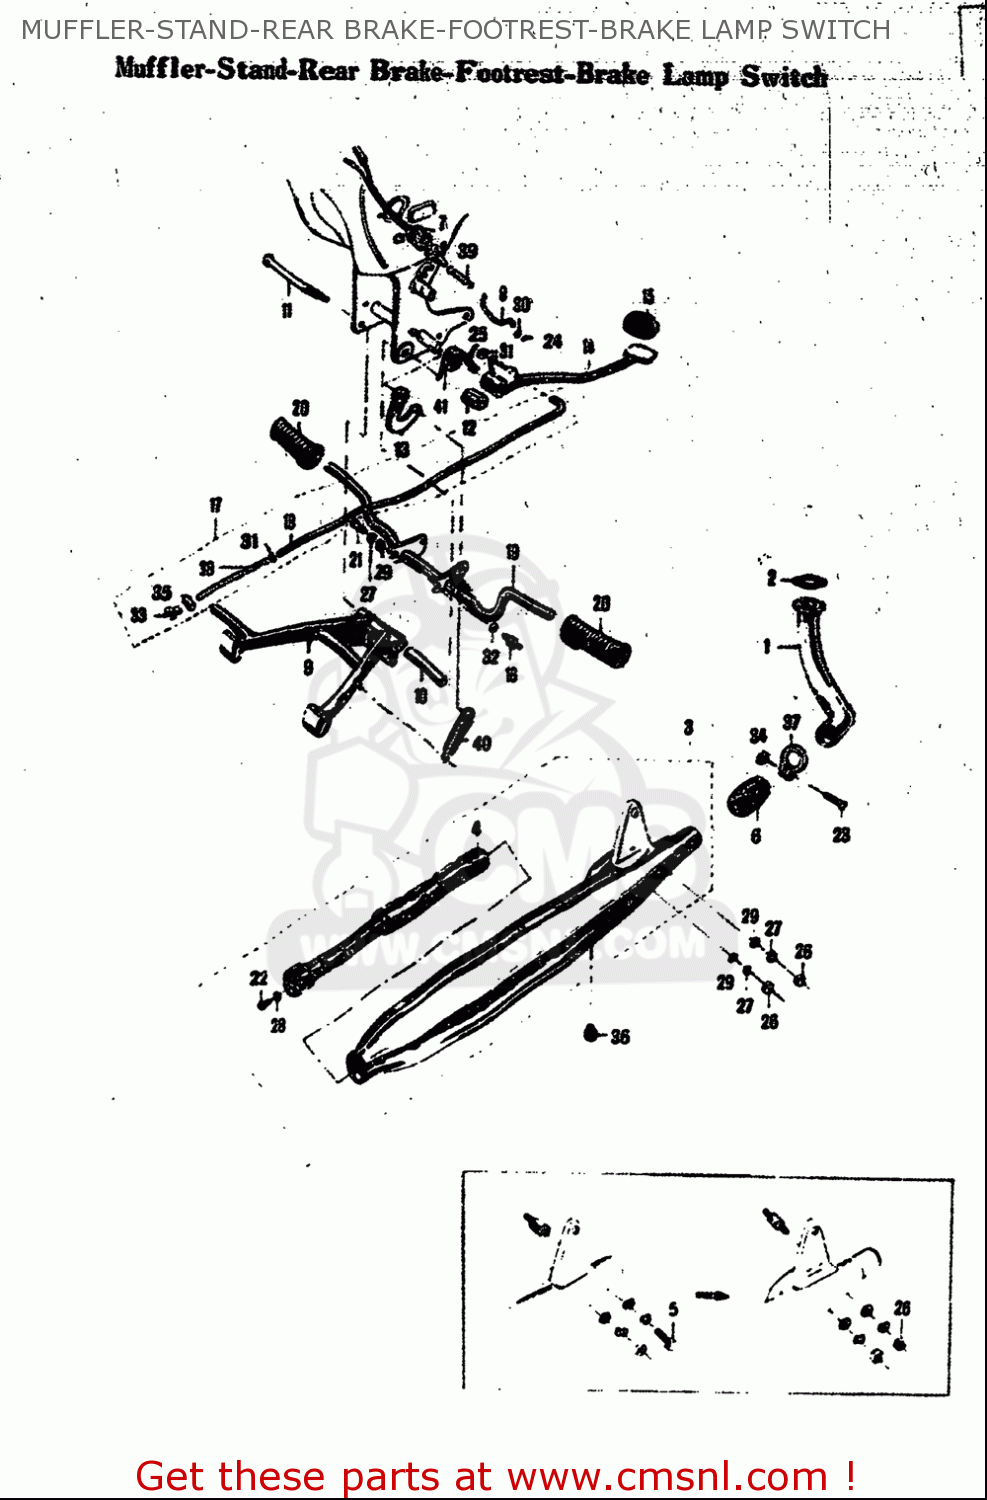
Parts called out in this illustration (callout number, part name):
10	SPACER
16	STOPPER,BRAKE PEDAL
20	RUBBER,FR FOOTREST
21	BOLT
22	SCREW(5X6)
24	PIN 20X10
26	NUT
27	WASHER,LOCK
28	WASHER
29	WASHER
30	WASHER
31	WASHER
32	WASHER
33	NUT
35	BRAKE ROD LEVER
36	CUSHION
38	SPRING
39	SPRING
40	SPRING
